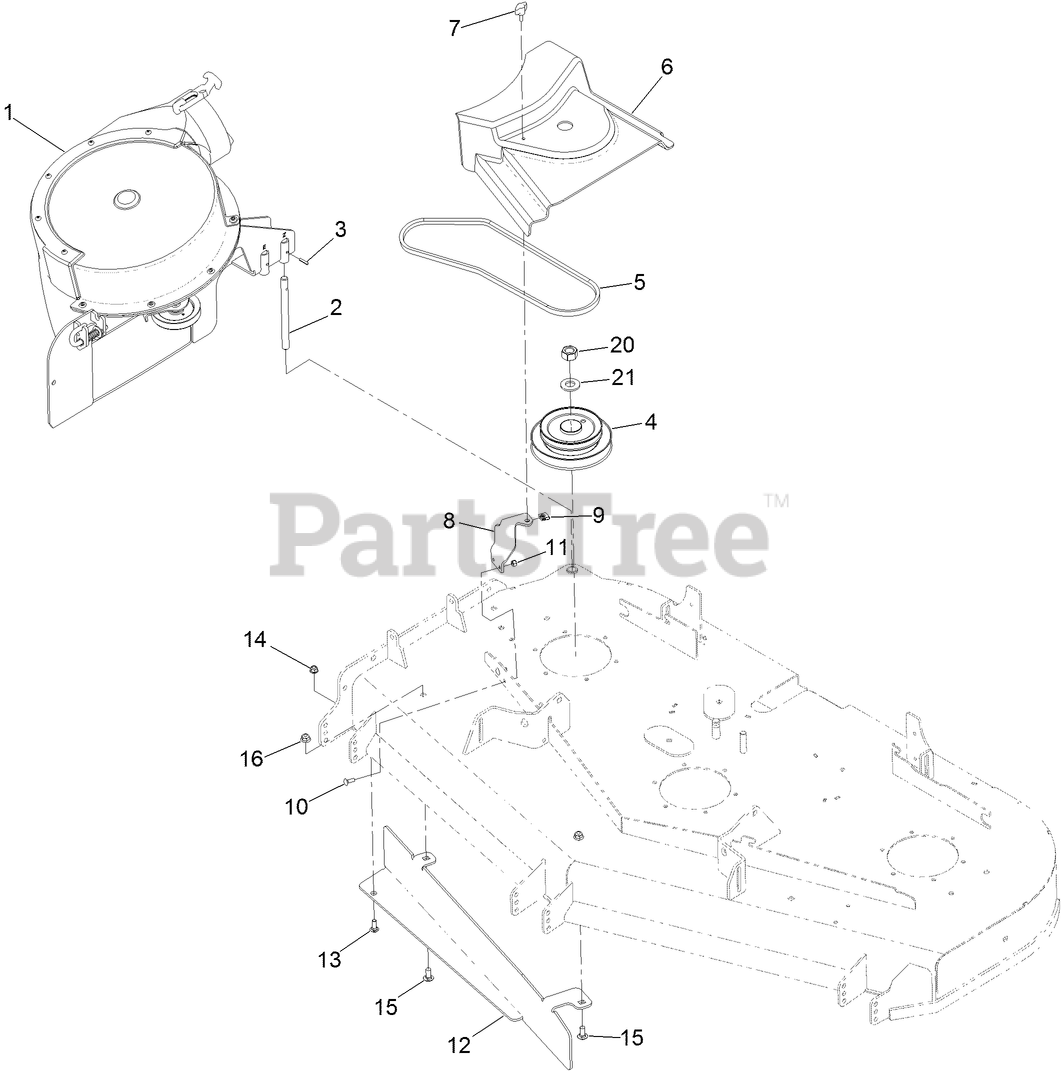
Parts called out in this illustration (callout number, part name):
1	BLOWER ASM
2	SHAFT-CATCHER, GRASS
3	PIN-ROLL
4	DRIVE-JACKSHAFT
5	BELT-4L SECTION
6	COVER-BELT
8	BRACKET-COVER, BELT
9	NUT-SPEED
10	BOLT-CARR
11	NUT-LOCK, NI
12	BAFFLE-BAGGER
13	SCREW-CARR
14	NUT-HF, NI
15	SCREW-CARR
16	NUT-HF, NI
20	NUT-HEX
21	WASHER
